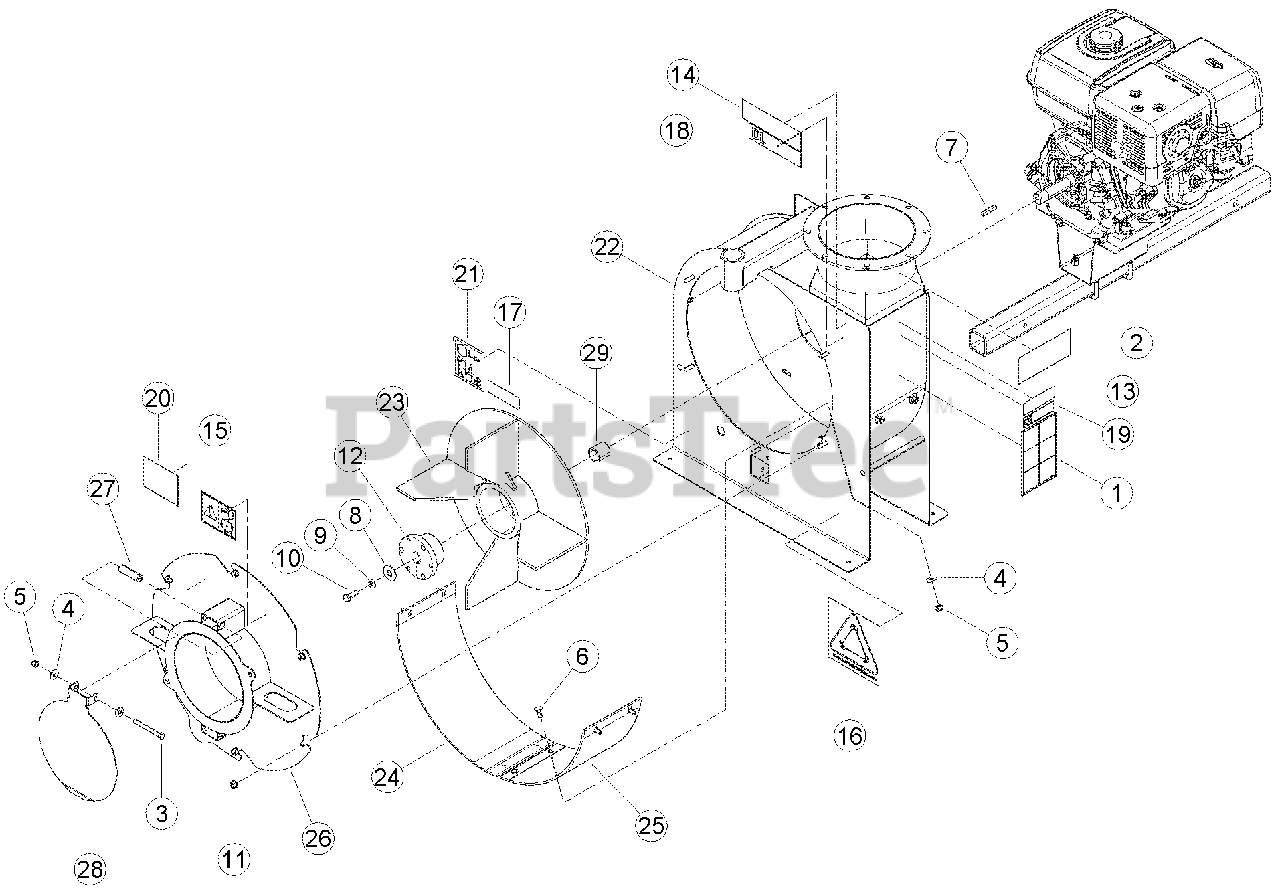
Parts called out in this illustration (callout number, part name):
1	DECAL, OPERATING INSTRUCTIONS ISO
2	DECAL, MUTILINGUAL MANUAL
3	BOLT, 5/16 X 3 HEX HD GR5 ZP
4	WASHER, 5/16 FLAT ZP
5	NUT, 5/16 NE NYLOCK ZP
6	BOLT, 5/16 X 3/4 CRG GR5 NC ZP
7	KEY, 1/4 SQUARE X 1-1/2 LONG PLAIN
8	WASHER, 1/2 GR8 USS ZP
9	WASHER, 3/8 GR8 USS ZP
10	BOLT, 7/16 X 1-1/2 HEX HD GR5 NF ZP
11	NUT, 5/16 FLANGE TOPLOCK
12	BUSHING SK 1-1/8"
13	DECAL, SERIAL NUMBER
14	DECAL, ECHO BEARCAT 6.82 X 1.90
15	DECAL, INSTRUCTION ISO
16	DECAL, COLLECT IT
17	DECAL, ATLANTIC BRIDGE LTD INFO
18	DECAL, MODEL DL10570
19	DECAL, DL10570 INFO
20	DECAL, INSTRUCTION ISO
21	DECAL, 138 DB
22	WELDMENT, FAN HOUSING
23	WELDMENT, FAN
24	LINER, WEAR
25	LINER, WEAR
26	WELDMENT, VACUUM INTAKE
27	SPACER, 5/8 OD X 11 GA X 2.13
28	SHIELD, INTAKE
29	SPACER, 1-1/2 OD X 3/16 WA X 1.92
